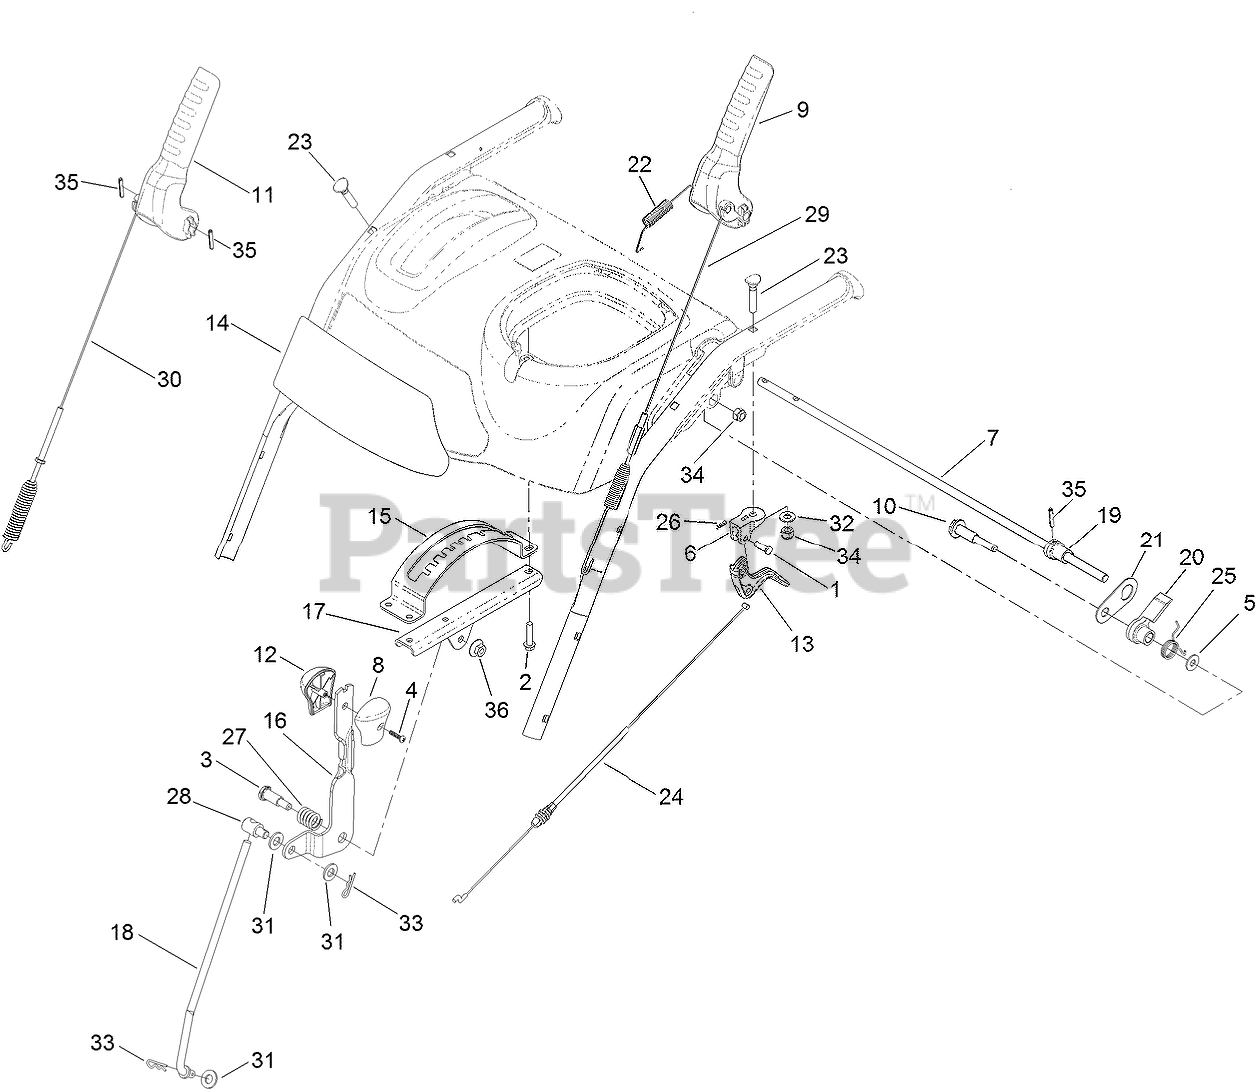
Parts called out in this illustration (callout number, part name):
1	PIN-CLEVIS
2	SCREW-PLASTITE
3	SCREW-SHOULDER
4	SCREW-PPH
5	WASHER-FLAT
6	MOUNT-CLUTCH, LEVER
7	ROD-LOCKOUT
8	KNOB-SHIFT, LH
9	LEVER-TRACTION
10	SCREW-SHOULDER
11	LEVER-AUGER
12	KNOB-SHIFT, RH
13	LEVER-CLUTCH
14	DECAL-CONTROL PANEL
15	GUIDE-SELECTOR, SPEED
16	SELECTOR-SPEED
17	BRACKET-SELECTOR, SPEED
18	ROD-SHIFT
19	CAM-LOCKOUT
20	LATCH-LOCKOUT
21	LINK-LOCKOUT
22	SPRING-TENSION
23	SCREW-HANDLE
24	CABLE-CLUTCH
25	SPRING-TORSION
26	PIN-HAIR
27	SPRING-COMPRESSION
28	TRUNNION-ROD
29	CABLE-TRACTION
30	CABLE-AUGER
31	WASHER-FLAT
32	WASHER-FLAT
33	PIN-COTTER
34	NUT-LOCK, NI
35	PIN-SPRING
36	NUT-HF
